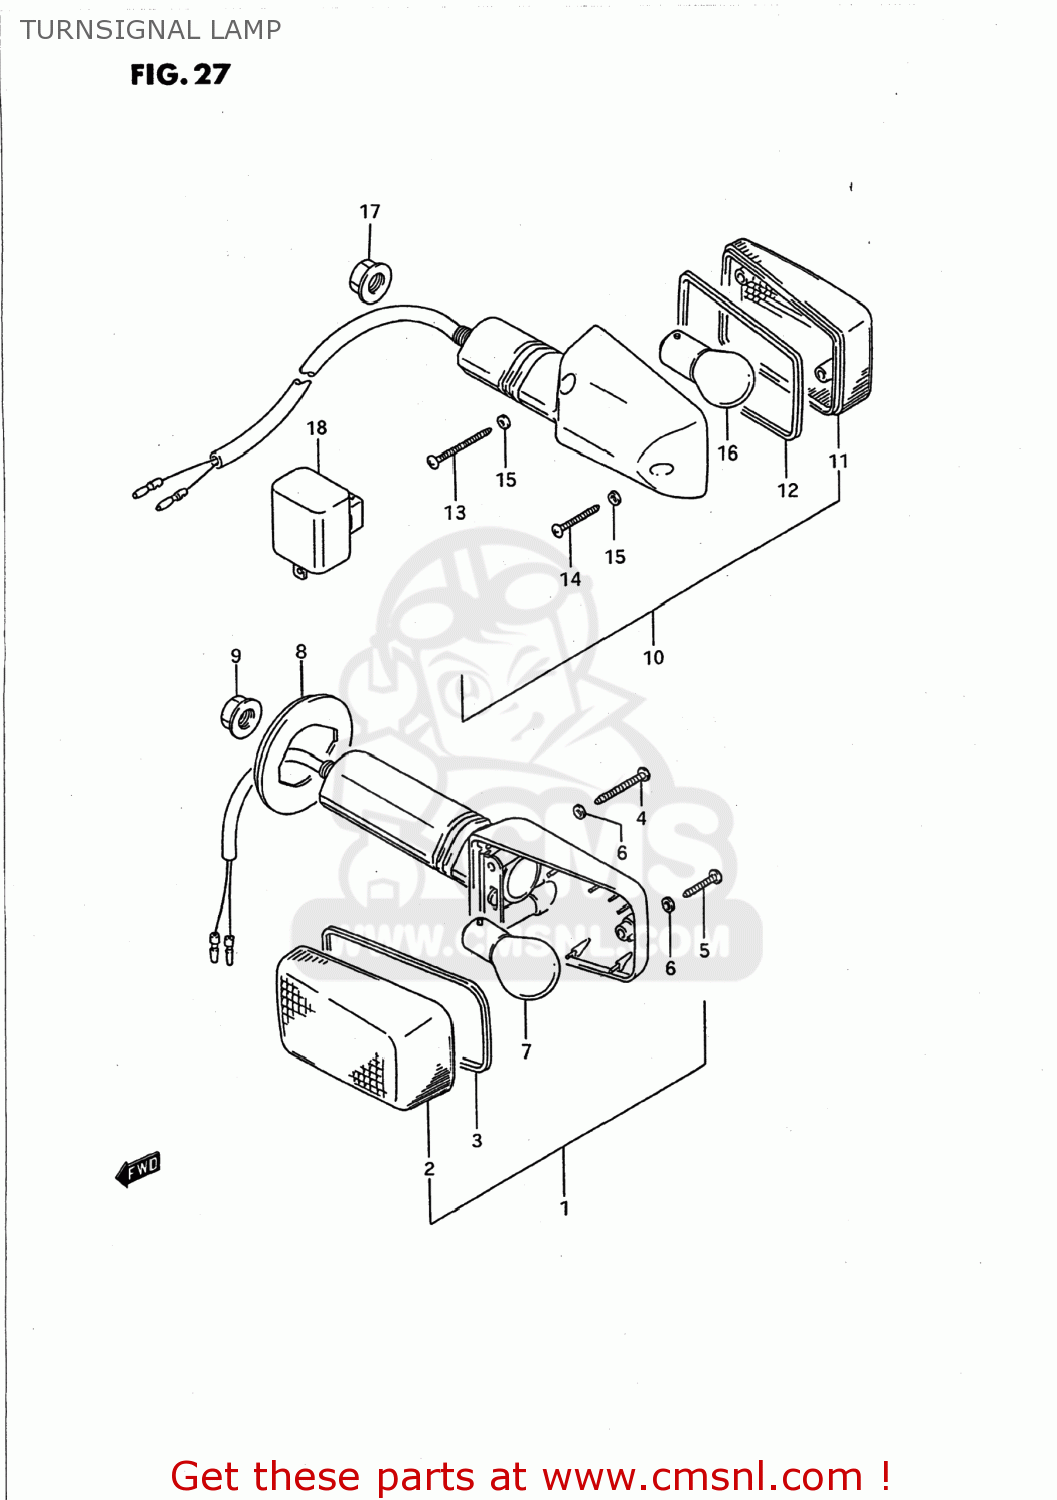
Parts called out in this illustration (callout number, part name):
1	LAMP ASSY,FR TURN SIGNAL
2	LENS
3	GASKET (NAS)
4	SCREW(3X30)
5	SCREW
6	GASKET (NAS)
7	BULB(12V21W)
8	GROMMET
9	NUT
10	LAMP ASSY,RR TURNSIGNAL
11	LENS
12	GASKET (NAS)
13	SCREW(3X30)
14	SCREW
15	GASKET (NAS)
16	BULB(12V21W)
17	NUT
18	RELAY,TURN SIGNAL
